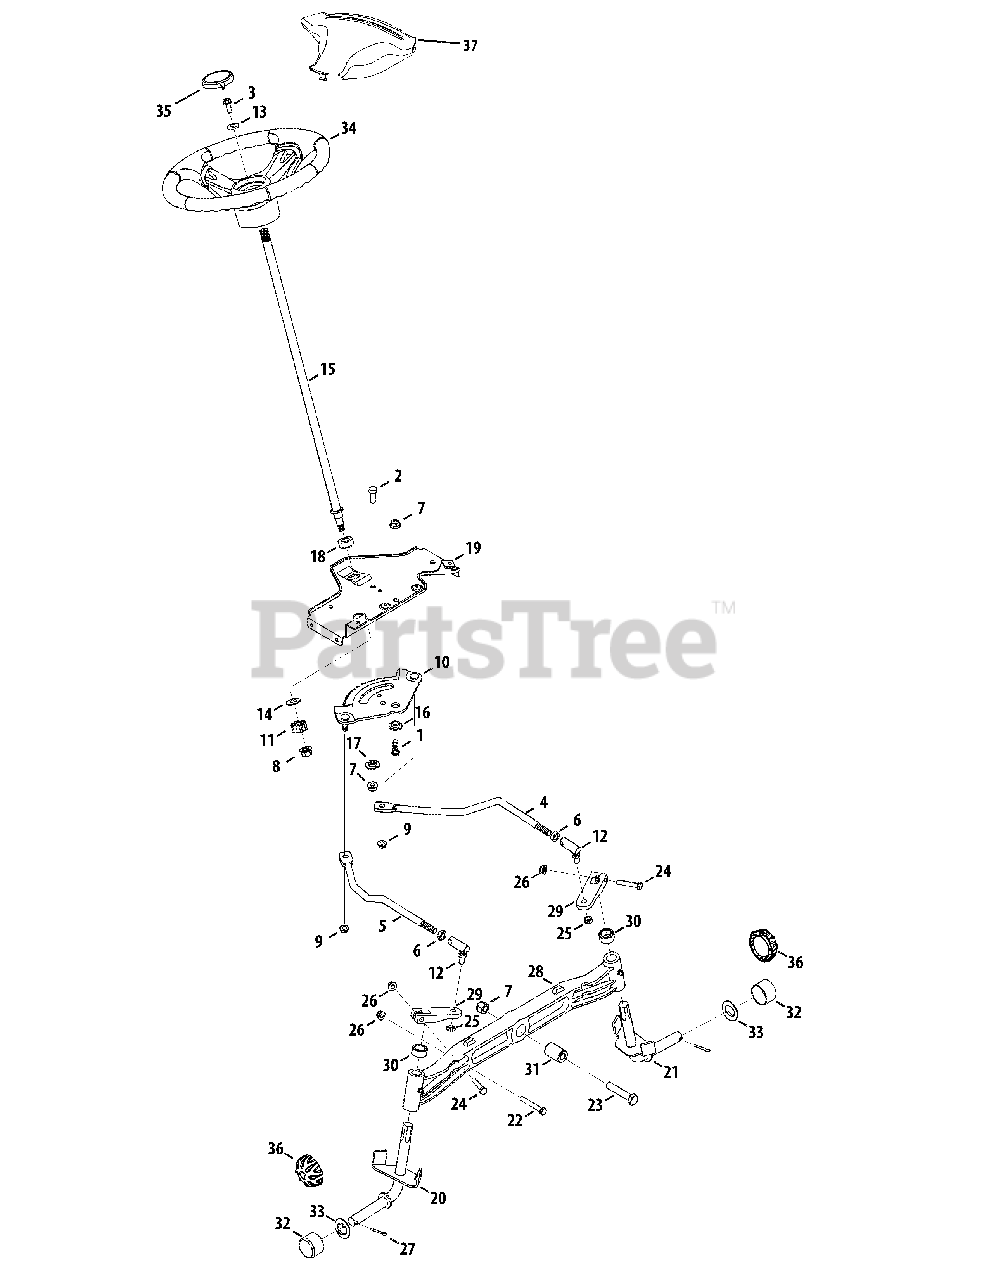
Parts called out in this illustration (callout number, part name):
1	Screw, 3/8-16 x 1.0
2	Hex Screw 3/16 x 1.00
3	Hex Screw 5/16-18 x 1.00 Special
4	Link, Drag LH
5	Link, Drag RH
6	Hex Jam Nut 7/16-20
7	Flange Lock-Nut 3/8-16 Gr. F Nylon
8	Flange Lock Nut, 7/16-20
9	Hex Flange L-Nut 5/16-18
10	Steering Gear, 11/90 Ratio
11	Steering Pinion Gear
12	Ball Joint, 7/16 - 20
13	Flat Washer .406 ID x .875 DE x .105
14	Fl. Washer .510 x 1.120 x .060
15	Steering Shaft .625 OD x 24.25
15	Steering Shaft .625 OD x 25.00
16	Shoulder Spacer .385 x 1.25 x .3025
17	Spacer .38x 1.375 Special
18	Hex Flange Bear ing 5/8
19	Steering Support Bracket
20	Axle Ass’y RH .750 Dia. (42" Deck)
21	Axle Ass’y LH .750 Dia. (42" Deck)
22	Hex Bolt 5/16-18 x 2.25
23	Hex Cap Screw, 3/8-16 x 2.5
24	Hex Screw 5/16-18 x 1.75" Lg.
25	Hex Cent L-Nut 3/8-24
26	Flange Locknut 5/16-18 Gr. F, Nylon
27	Cotter Pin 5/32" Dia.
28	Pivot Bar (cast)
29	Steering Block
30	Spacer .710 ID x .125 OD x .56
31	Spacer .385 x 1.0 x 1.5075
33	Flat Washer .350 x 1.559 x .062
34	Steering Wheel, Standard Grip
35	Steering Wheel Cap w/sprig logo
36	Hub Cap
37	Steering Wheel Cover (w/sprigs)
